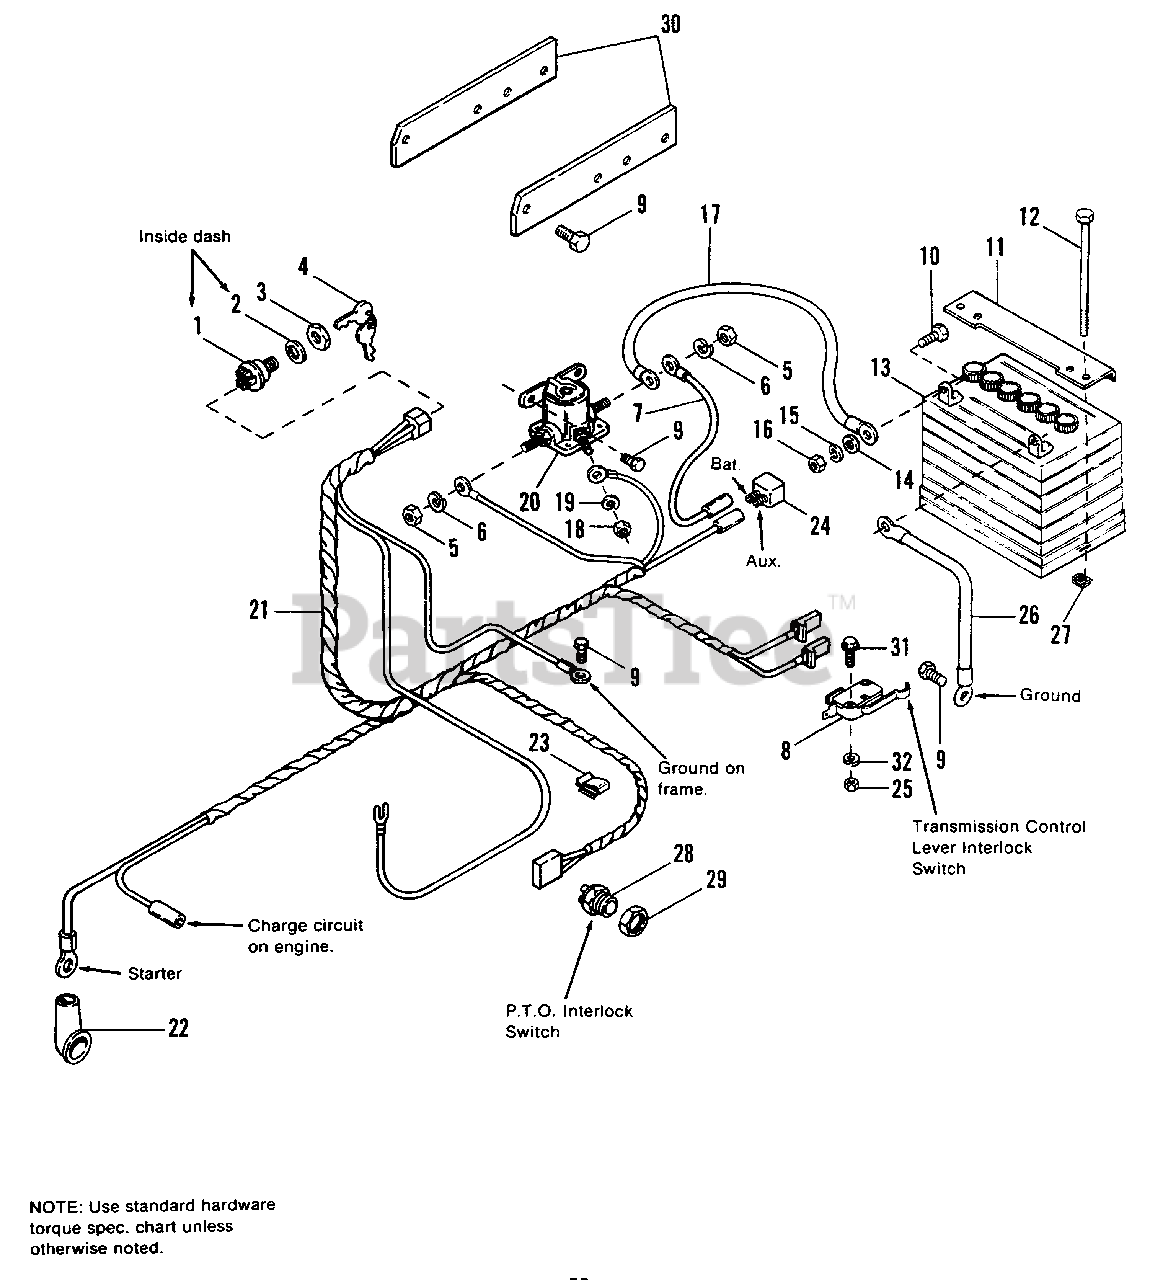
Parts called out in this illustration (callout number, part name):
1	SWITCH, Ignition (Incl. Ref. Nos. 1, 2, 3 & 4)
2	LOCKWASHER, Internal Tooth, 5/8
3	NUT, 5/8-32
4	KEYS, Set of 2
5	NUT, Hex, 5/16-18
6	LOCKWASHER, 5/16
8	SWITCH, Interlock
9	SCREW, Taptite, 1/4-20 x 3/8
10	CAPSCREW, Hex, 1/4-20 x 3/4
11	CLAMP, Battery
12	CAPSCREW, Hex, 1/4-20 x 7-1/2
13	BATTERY SERVICE KIT, 39 Amp.
14	WASHER, 1/4
15	LOCKWASHER, 1/4
16	NUT, Hex, 1/4-20
18	NUT, Hex, #10-32
19	LOCKWASHER, Ext. #10
21	HARNESS, Wiring
22	COVER, Terminal
23	CLIP, Speed
24	CIRCUIT BREAKER
25	NUT, Hex, #5-40
27	NUT, Retainer, 1/4-20
28	SWITCH, Interlock
29	LOCKNUT, 9/16-18
30	BRACE, Shift Panel
31	SCREW, Rd. Hd., Phil. #5-40 x 3/4
32	LOCKWASHER, #5
